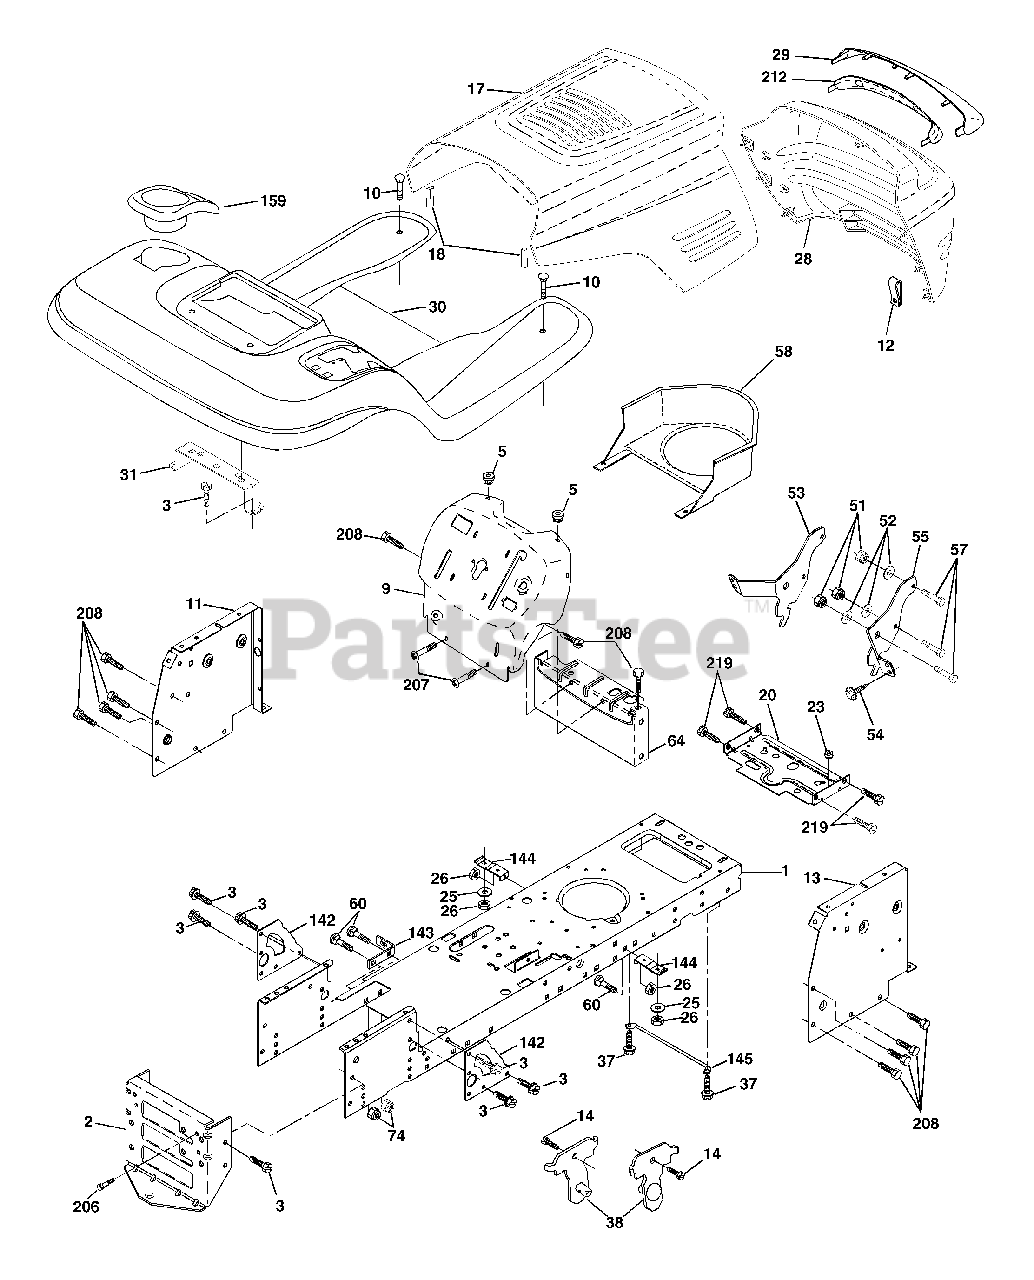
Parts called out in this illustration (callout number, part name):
1	Chassis Stamping
3	Screw 3/8-16x3/4
9	Dashboard
10	Bolt Rdhd Sqnk 3/8-16 Unc x 1
11	Panel Dash Lh
12	Clip Tinnerman Grille
13	Panel Dash Rh
14	Screw Thdrol 3/8-16 x 1/2
17	Hood
20	Plate Mtg Battery/Fuel Tank
25	Washer 13/32 x 13/16 x 12 Ga.
26	Nut Lock w/Insert 3/8-16 UNC
28	Grille Lens Asm
29	Lens
30	Fender
37	Screw Thdrol 5/16-18 x 1/2
38	Bracket Asm Pivot Mower Rear
51	Nut Lock w/Insert 1/4-20
52	Washer 9/32 x 7/8 x 16 Ga.
53	Bracket Grille Lh
54	Screw Hex Wshd 8-18 x 7/8
55	Bracket Grille Rh
57	Bolt Fin Hex 1/4-20 Unc x 3/4
60	Bolt RDHD SQNK 3/8-16 x 3/4
64	Dash Lower Stlt
74	Nut Crownlock 3/8-16
142	Plate Reinforcement Stlt
143	Bracket Swaybar Chassis
144	Bracket Ft Rest
145	Rod Pivot Chassis Hood
159	Cupholder YTGT Grey
206	Bolt Shoulder 5/16-18 TT
207	Screw Thdrol 5/16-18 x 1/2 TYTT
208	Screw Thdrol 3/8-16 x 1/2 Ty-TT
212	Insert Lens Reflect
